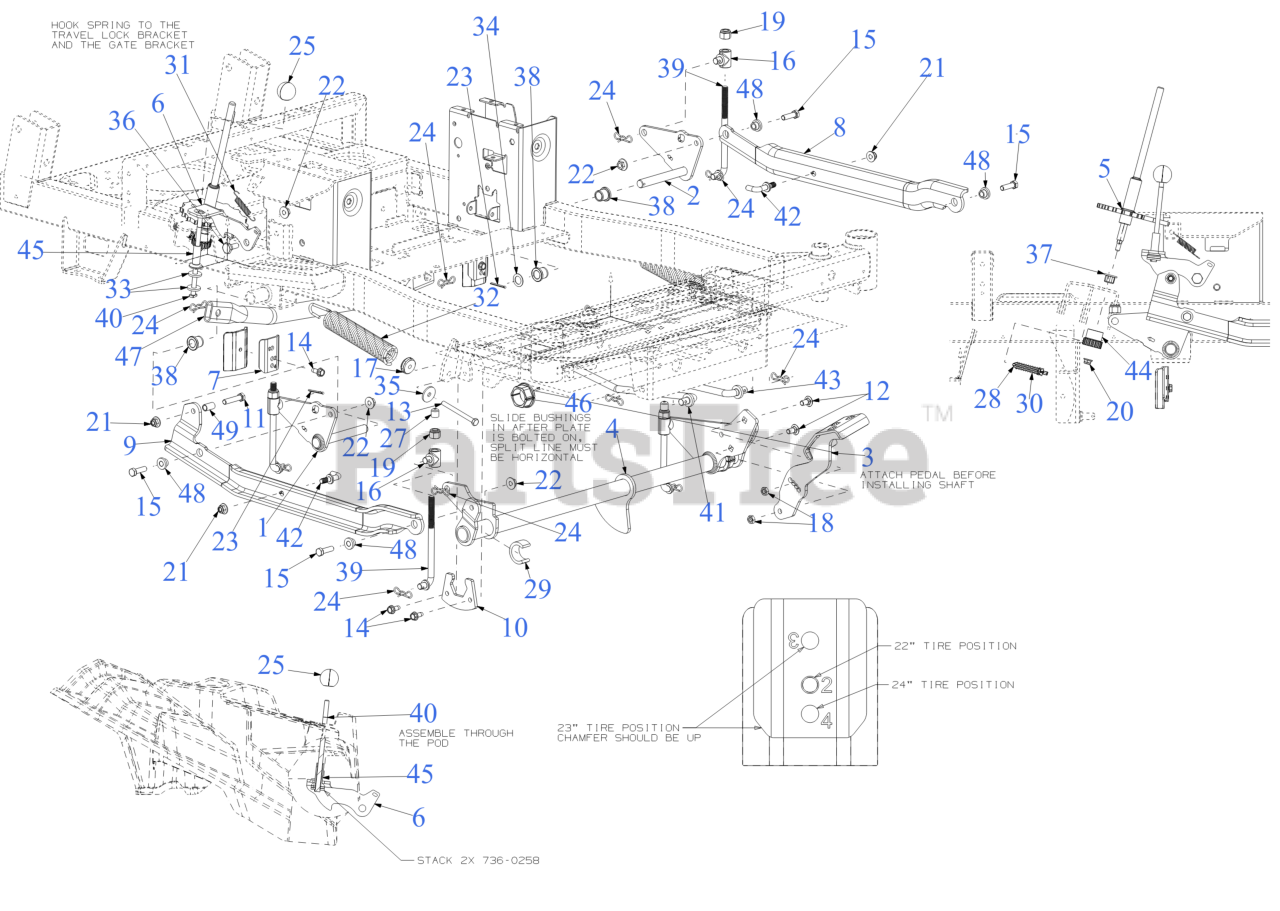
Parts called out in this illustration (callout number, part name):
1	BELLCRANK BRACKET (RH)
2	BELLCRANK BRACKET (LH)
3	DECK LIFT PEDAL
4	LIFT TUBE (FRONT)
5	DECK HEIGHT ADJUSTMENT ROD
6	TRAVEL LOCK PLATE
7	UPSTOP BRACKET
8	LIFT LINK (LH)
9	LIFT LINK (RH)
10	LIFT TUBE BRACKET
11	HEX SCREW 3/8-16 x 1.75 GR5
12	CARRIAGE BOLT 3/8-16 x .750 GR5
13	SCREW 5/16-18 x 3.50 GR5
14	SCREW 5/16-18 x .750
15	SCREW 3/8-16 x 1.25 GR5
16	LIFT ROD FERRULE
17	LIFT SPRING INSERT
18	HEX JAM NUT 3/8-16 GR5
19	HEX LOCK NUT NYLON
20	FLANGE LOCK NUT 5/16-18
22	FLANGE LOCK NUT
23	COTTER PIN
24	BOW TIE COTTER PIN
27	LIFT ROD END CAP
28	DETENT PLUNGER
29	LIFT TUBE SPACER
30	COMPRESSION SPRING .531 OD 1.75 LG
31	EXTENSION SPRING 2.675"
32	EXTENSION SPRING
33	FLAT WASHER .385 x 1.00 x .135
34	FLAT WASHER
35	WASHER-5/16 x 1.25X 1.27
36	SHOULDER SCREW
37	HEX FLANGE BEARING .506ID x .590LG
38	FLANGE BUSHING
39	DECK LIFT ROD 6.875"
40	TRAVEL LOCK ROD
41	DECK CONTROL ROD (RH)
42	LIFT SPRING MOUNTING ROD
43	DECK CONTROL ROD (LH)
44	DECK HEIGHT DETENT HUB
45	LOCK ROD SLEEVE SPACER
46	HEX FLANGE BEARING
47	DECK STABILIZER TUBE
48	SHOULDER SPACER 0.39x0.575x0.312
49	SPACER .380x.500x.875
